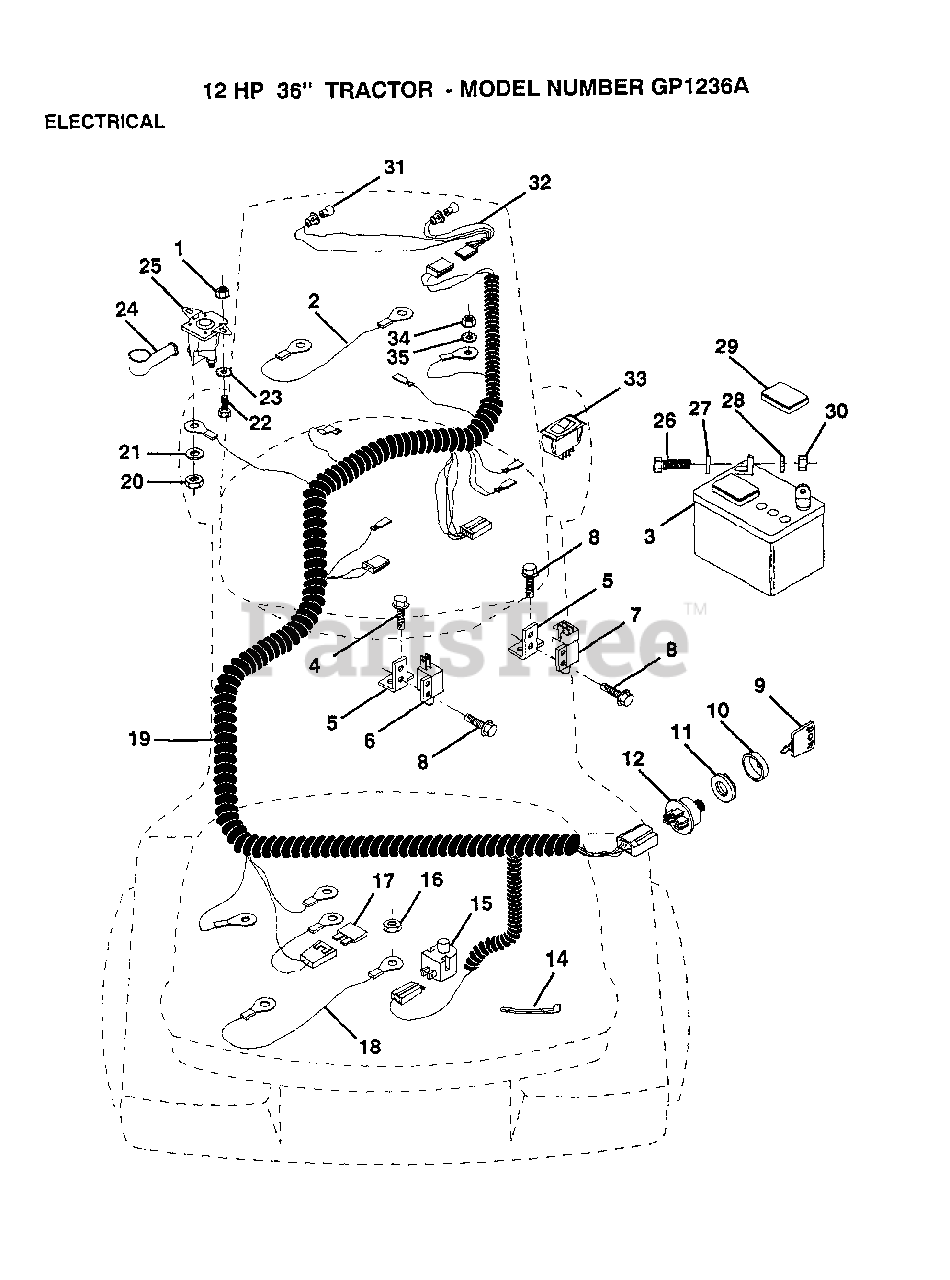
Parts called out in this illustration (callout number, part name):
1	NUT
2	CABLE ASM.
5	BRACKET LT
6	SWITCH-INTER. GT
7	SWITCH INTERLOCKT
8	SCREW
9	KEY
11	NUT IGNITION
14	WIRE TIE
15	SWITCH SEAT
17	FUSE HYT
18	CABLE ASSY
20	NUT
22	BOLT
26	BOLT LT
27	WASHER
28	LOCKWASHER
29	"CAP,BATTERY "
33	SWITCH LT
34	NUT
35	LOCKWASHER
